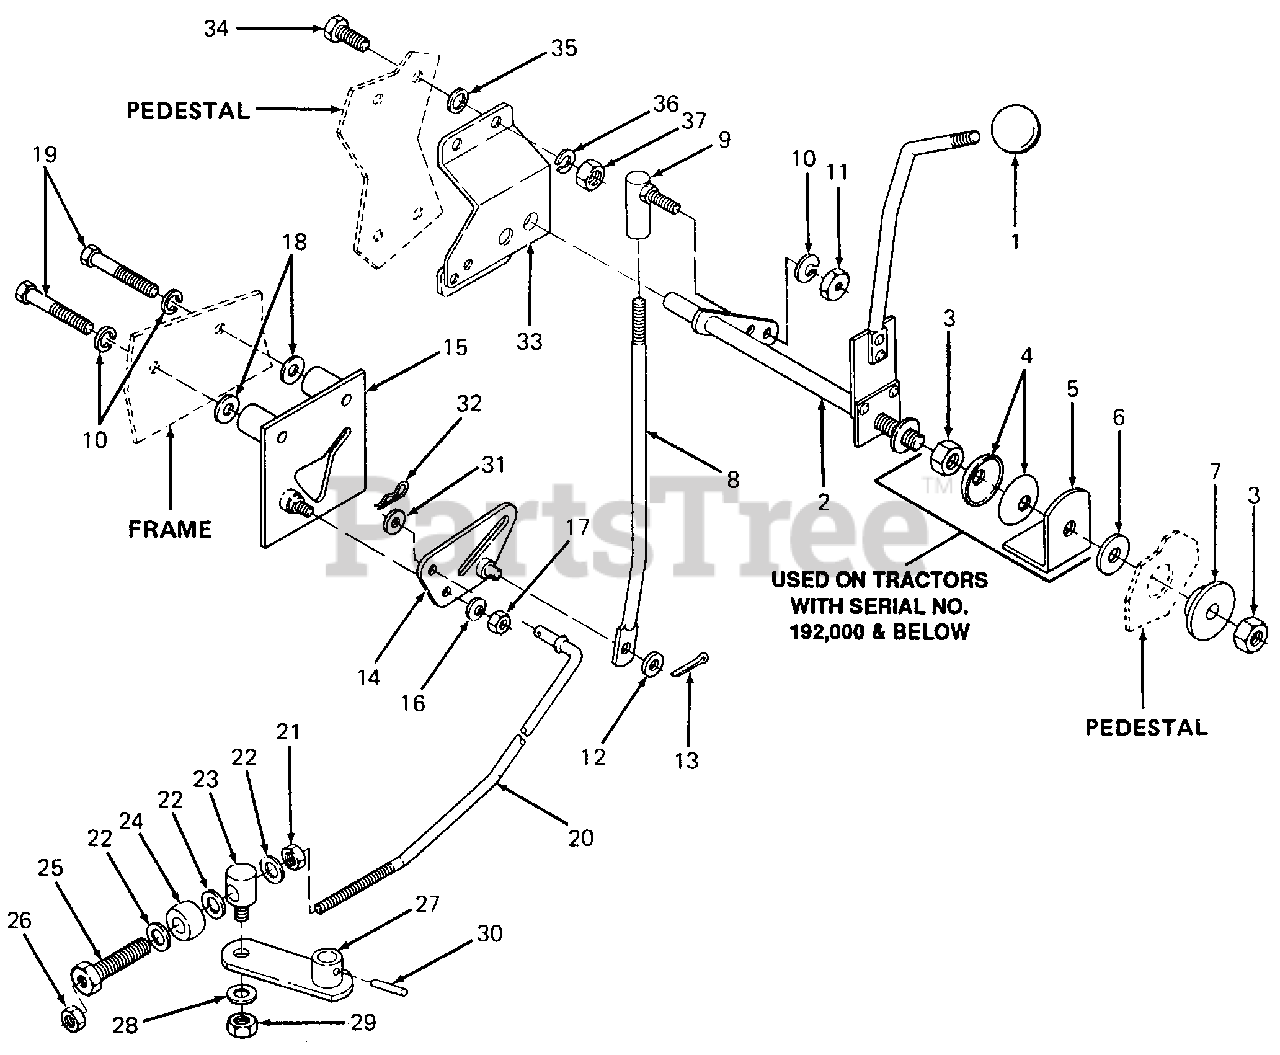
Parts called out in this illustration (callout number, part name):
1	Knob, Control
2	Shifter Assembly
3	Nut, Hex Jam Patch, 1/2-20
4	Washer, Bell
5	Bracket, Friction
6	Washer, Friction
7	Spacer, Shoulder
8	Rod, Upper Shift Control
9	Ball Joint
10	Washer, Lock, 3/8
11	Nut, Hex Patch Lock, 3/8-24 GR5
12	Washer, Flat, .406 X .75 X .063 Thk
13	Pin, Cotter, 1/8 Dia X .75 Lg
14	Lever, Cam
15	Plate, Cam
16	Washer, Bell
17	Nut, Hex Center Lock Jam, 3/8-24
18	Washer, Flat, .378 X 1.00 X .125 Thk
19	Screw, Hex Cap, 3/8-24 X 1.0 Lg
20	Rod, Hydro Control
21	Nut, Hex Patch Lock, 7/16-20
22	Washer, Flat
24	Washer, Rubber, .38 X .87
25	Stud, Adjustment
26	Nut, Hex, 5/16-24 GR5
28	Washer, Flat, .320 X .60 X .06 Thk HDN
29	Nut, Hex Patch Lock, 5/16-18
30	Pin, Slotted Roll, 5mm X 30mm Lg
31	Washer, Flat, .34 X .68 X .062 Thk
32	Pin, Internal Cotter
33	Bracket, Clutch Handle
34	Screw, Hex Cap, 1/4-20 X .62 Lg GR5
35	Washer, Flat, .281 X .75 X .105 Thk
36	Washer, Lock, 1/4
37	Nut, Hex, 1/4-20 GR5
